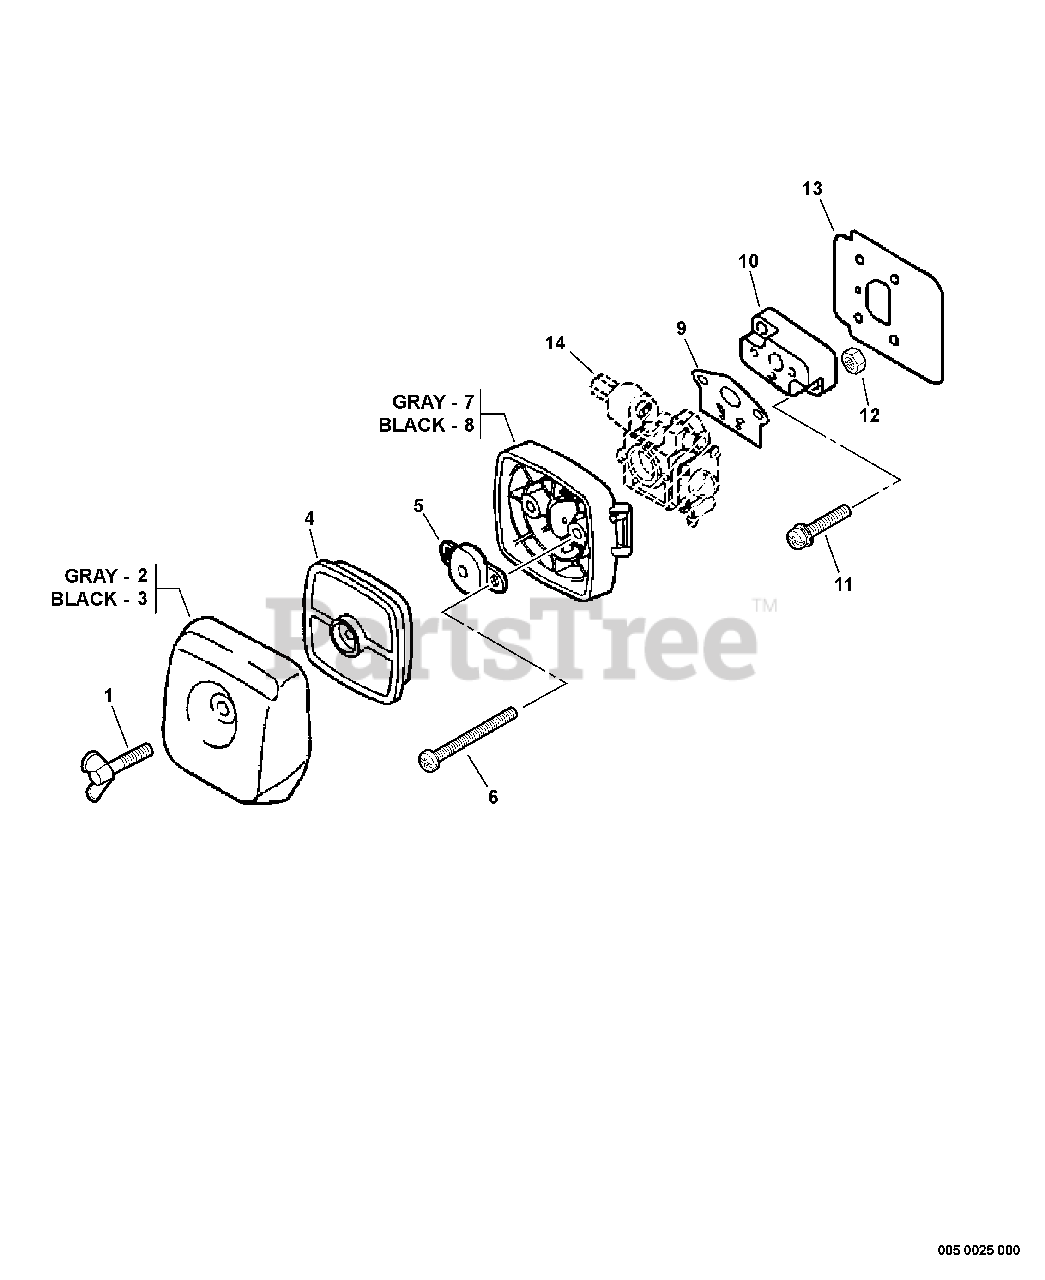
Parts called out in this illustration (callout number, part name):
1	THUMBSCREW
2	COVER, AIR FILTER - GRAY
3	COVER, AIR FILTER - BLACK
4	FILTER, AIR - SINGLE LAYER
5	PLATE, PREVENT
6	SCREW - 5X65
7	CASE, AIR FILTER - GRAY
8	CASE, AIR FILTER - BLACK
9	GASKET, INTAKE
10	INSULATOR, INTAKE
11	SCREW - 5X20
13	SHIELD, INTAKE
14	CARBURETOR
